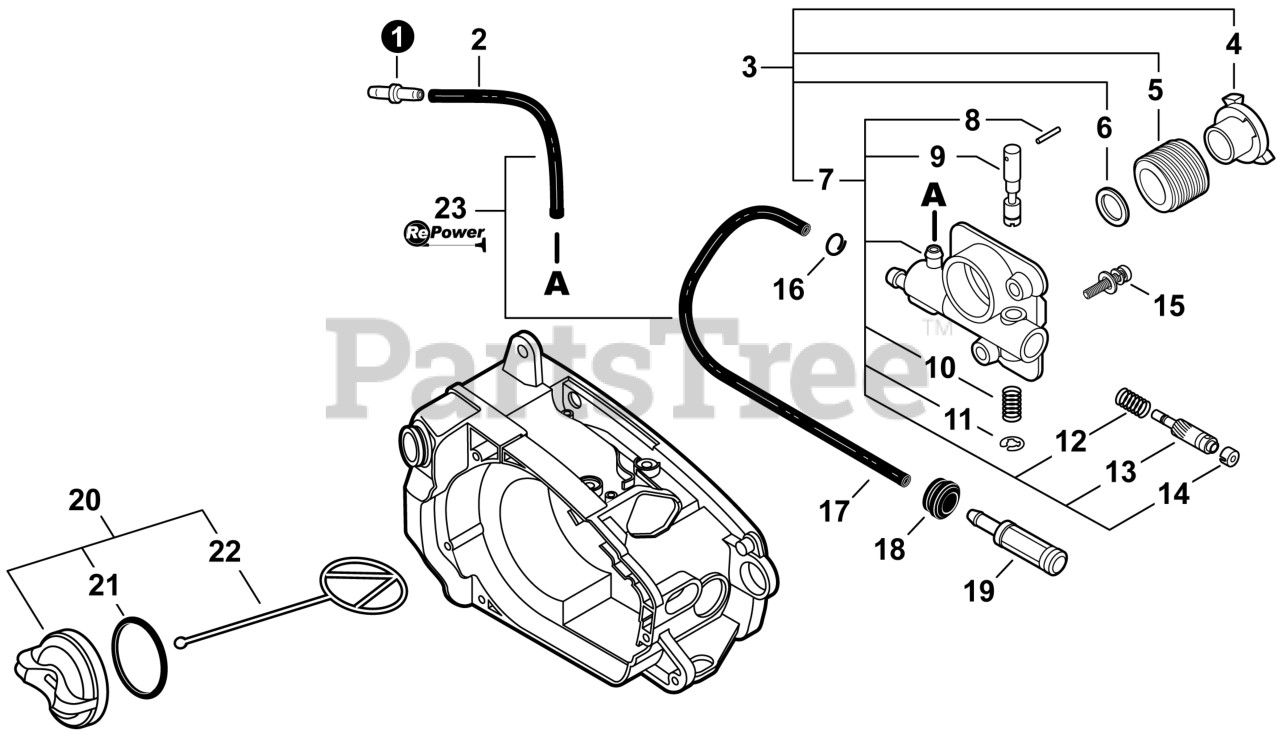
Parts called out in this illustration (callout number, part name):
1	CONNECTOR, PIPE
2	PIPE, 3×6×45 BLACK
3	AUTO-OILER ASSY
4	COLLAR 10
5	GEAR, WORM
6	WASHER 10.5×17.4×1.8
7	AUTO-OILER
8	PIN, SPRING
9	ADJUSTER, OILER
13	PLUNGER ASSY
14	CAP, OIL PUMP
15	SCREW 4×12
16	CLIP Ø6.5 MM
17	PIPE, FUEL 3×6×150
19	FILTER, OIL
20	CAP ASSY - BLACK
21	O-RING 18
22	FUEL CAP CONNECTOR (L=60MM)
23	BULK PIPE - 3×6 MM BLACK (4 PIECES×2 M)
